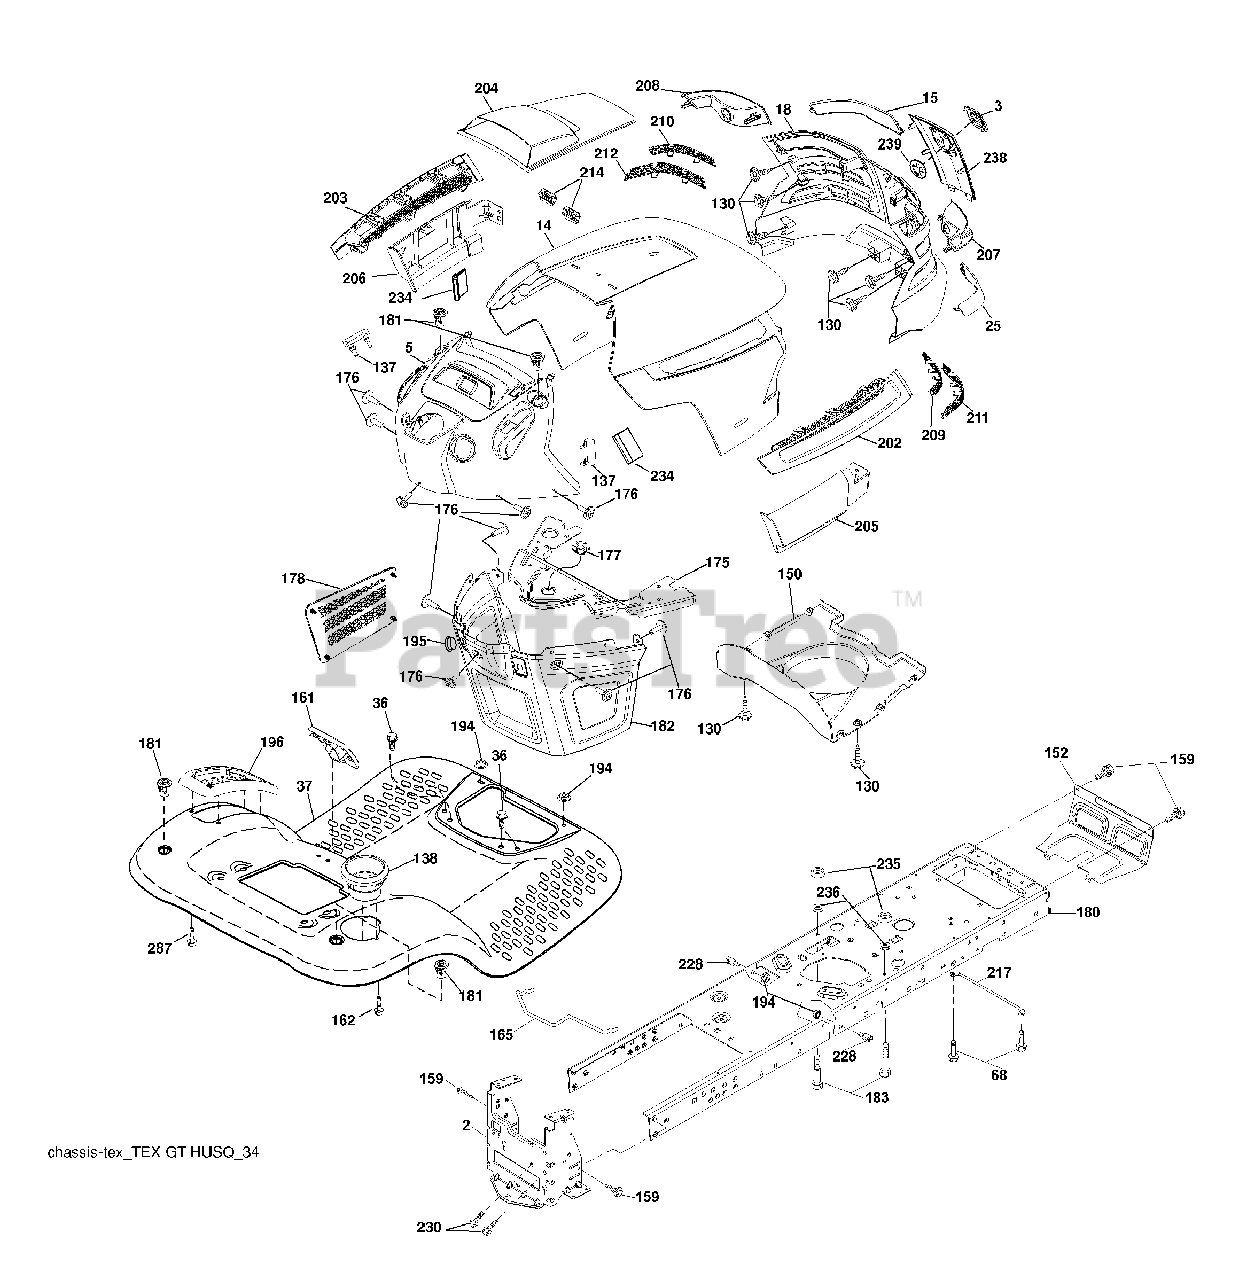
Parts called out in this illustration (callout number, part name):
3	Logo
7	Bolt Shoulder
14	Hood
18	Grille Asm.
36	Screw 5/16-18 x 3/4
68	Screw 5/16-18 x 1/2
130	Screw #10 x 0.750 BOS Thread
137	Bumper Dash
138	Cupholder
152	Shield Browning
159	Screw Hex Wsh Thdr 3/8-16 x 3/4
161	Window Fuel
165	Support Tank Rear
175	Crossmember
176	Screw 10-24 x 5/8
177	Bushing Steering
178	Cargo Net Asm.
180	Chassis
181	Bushing Mtg. Fender Crgo
182	Dash Lower
183	Bolt Fin Hex 5/16-18 unc x 1-1/4
194	Nut Lock Hex Flange 5/16-18
195	Plug Hole Dash Lower
196	Console Asm. Deck Lift
202	Vent Side Hood RH
203	Vent Side Hood LH
204	Vent Top Hood
205	Skirt Hood Side RH
206	Skirt Hood Side LH
209	Insert Hex Top RH
210	Insert Hex Top LH
211	Insert Hex Bottom RH
212	Insert Hex Bottom LH
214	Clip Retainer Tinner
228	Stud Fastner
230	Bolt Shoulder
234	Bumper Hood
235	Spacer Fender
236	Nut Lock 5/16-18 unc
287	Screw Hex Washead 1/4-20 x 3/8
